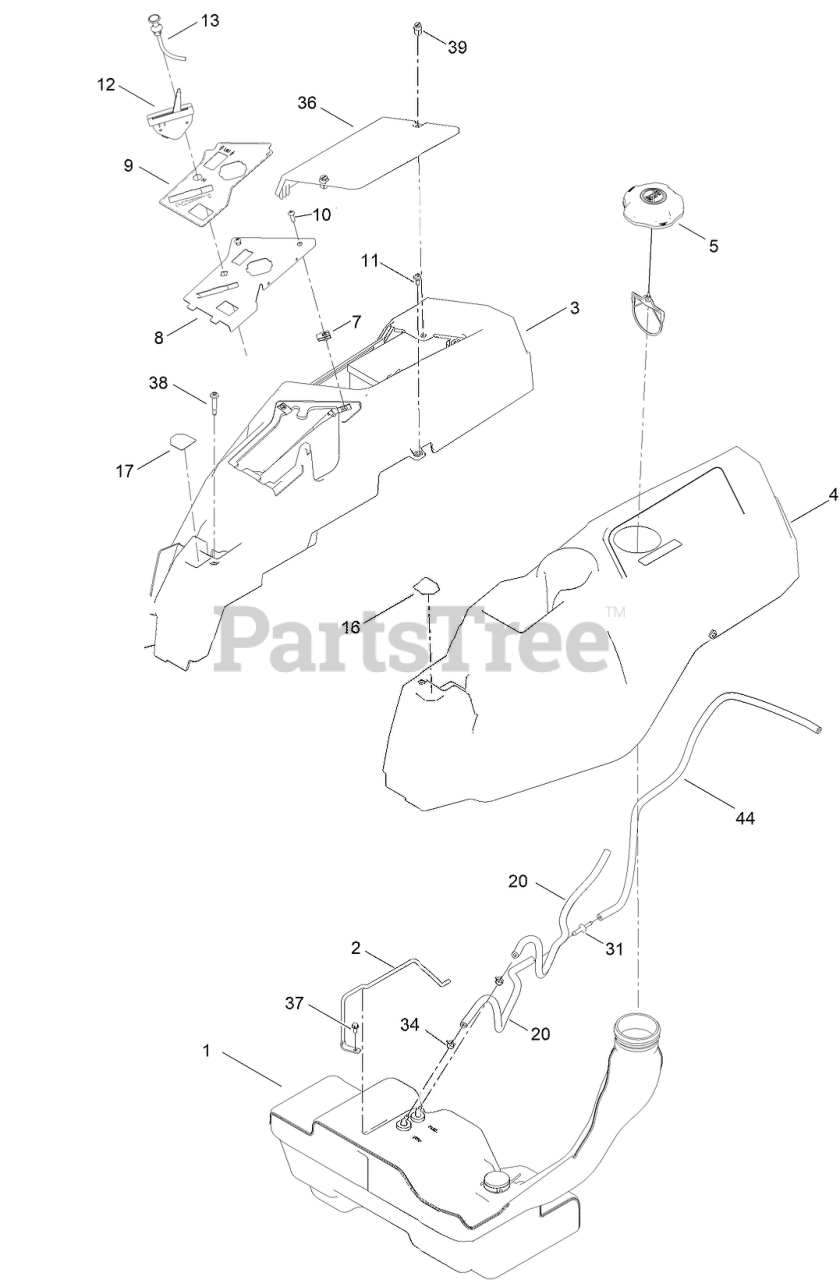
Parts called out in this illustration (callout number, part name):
1	FUEL TANK ASM
2	ROD-HOLD DOWN
3	POD-RH
4	POD-LH
5	CAP-FUEL, RATCHETING
8	PANEL-CONTROL
9	DECAL-PANEL, CONTROL
10	SCREW-PRH
11	SCREW-SHOULDER
12	CABLE-THROTTLE
13	CABLE-CHOKE
16	DECAL-LEVER, CONTROL (LH)
17	DECAL-LEVER, CONTROL (RH)
20	HOSE-FUEL
31	ADAPTOR-ORIFICE
34	CLAMP-HOSE
36	COVER-BATTERY
37	SCREW-HWH
38	SCREW-SHOULDER
39	FASTENER
44	HOSE-FUEL
